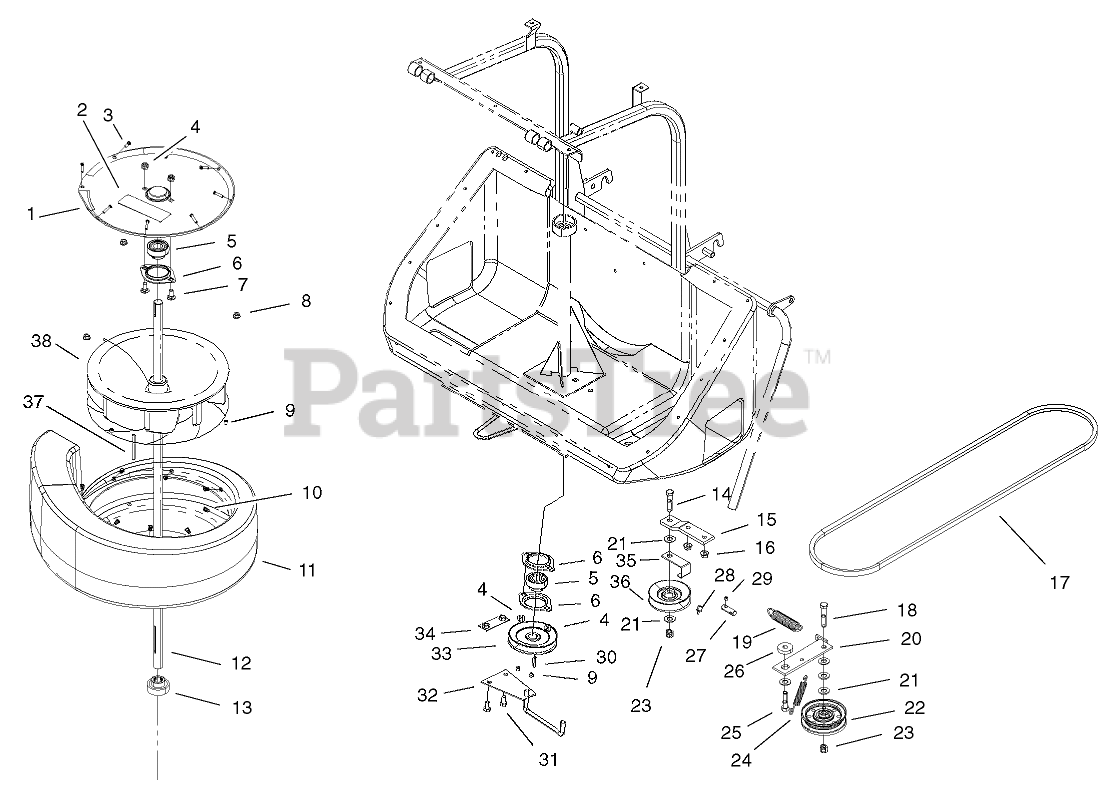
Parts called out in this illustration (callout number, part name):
1	COVER-SCROLL
2	DECAL-HAZARD, ADD WEIGHT
3	SCREW-PPH
4	NUT-LOCK, NI
5	BEARING
6	FLANGE
7	BOLT-CARR
8	NUT-HF
9	SCREW-SET, HSH
10	NUT-INSERT
11	SCROLL
12	SHAFT
13	BEARING
14	SCREW-HH
15	Bracket
16	NUT-HF
17	Belt-V
18	SCREW-HH
19	Spring-Extension
20	Arm-Idler
21	WASHER-FLAT
22	IDLER-FLAT
23	NUT-LOCK, NI
24	Spring-Extension
25	SCREW-HH
26	WASHER-FLANGE
27	END-CABLE
28	Grommet-Cable
29	SCREW-SET, HSH
31	SCREW-HH
32	Guide-Belt
33	PULLEY-V
34	Plate-Mounting
35	Guide-Belt
36	Pulley-V
